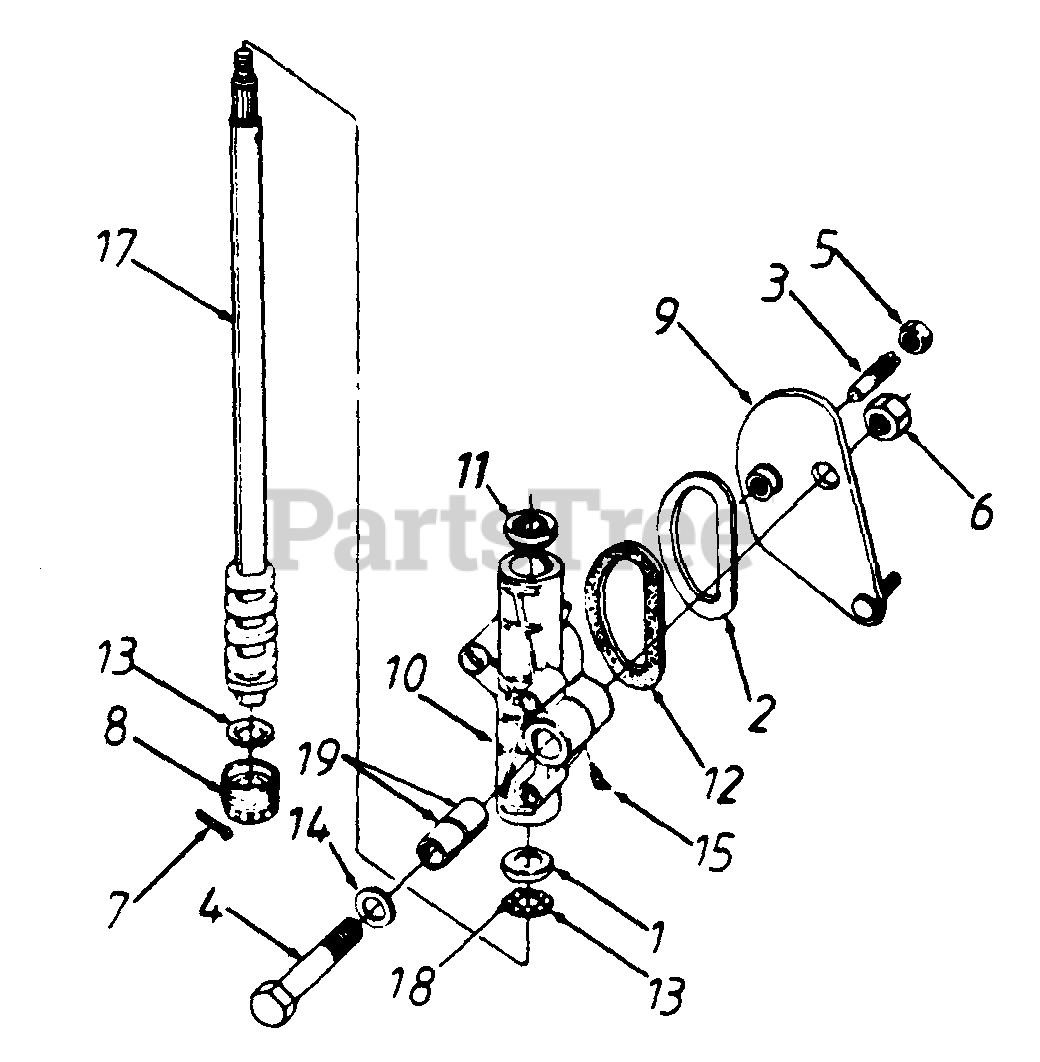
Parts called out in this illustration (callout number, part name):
1	Bearing Cup
2	Seal Retainer
3	Cam Follower
4	Pivot Shaft
5	Hex Jam Nut 9/16-18 Thd.
6	Hex Crown L-Nut 5/8-18 Thd.
7	Cotter Pin 1/8" Dia.
8	Adjustment Plug Ass'y.
9	Steering Arm Ass'y.
10	Steering Gear Hsg.
11	Oil Seal
12	Seal
13	Ball Retainer
14	Fl-Wash. .781" I.D. x 1.25" O.D.
15	Grease Fitting
17	Steering Shaft Ass'y.
18	Ball Bearing
19	Housing Bushing
